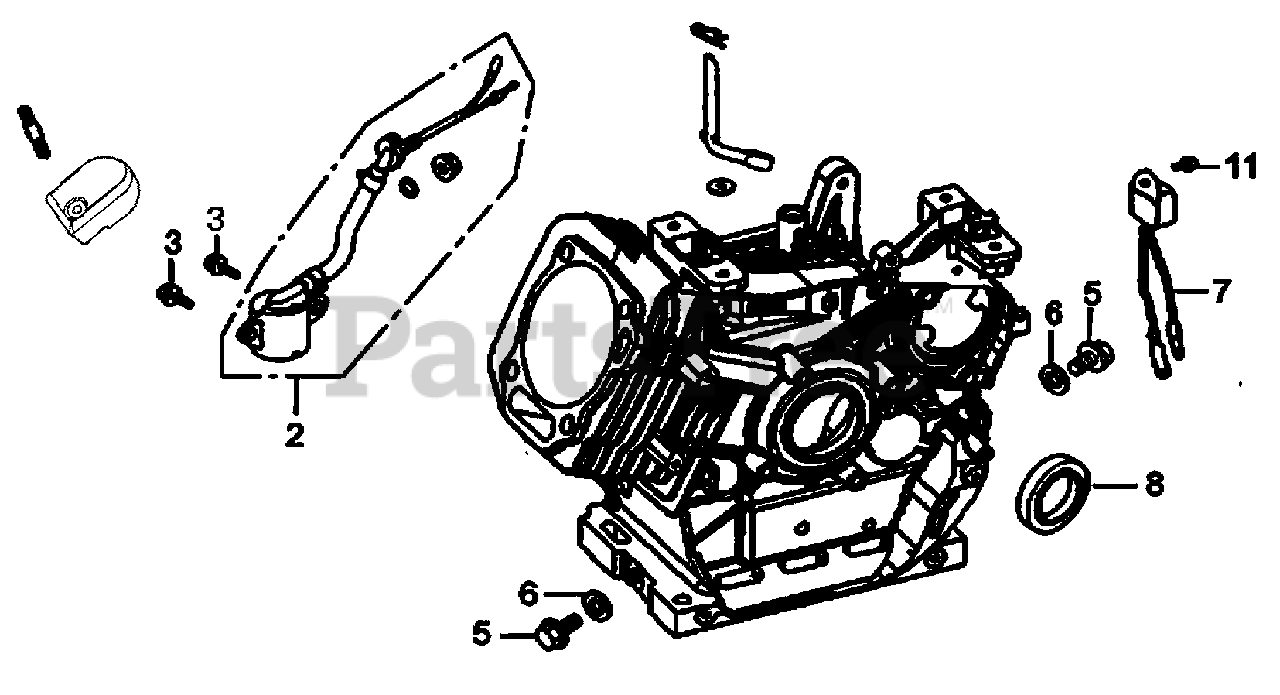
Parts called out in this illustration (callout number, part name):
2	SWITCH ASSY., OIL LEVEL
3	BOLT, FLANGE
5	BOLT, DRAIN PLUG
7	ALERT UNIT, OIL
8	SEAL, OIL
11	BOLT, FLANGE
